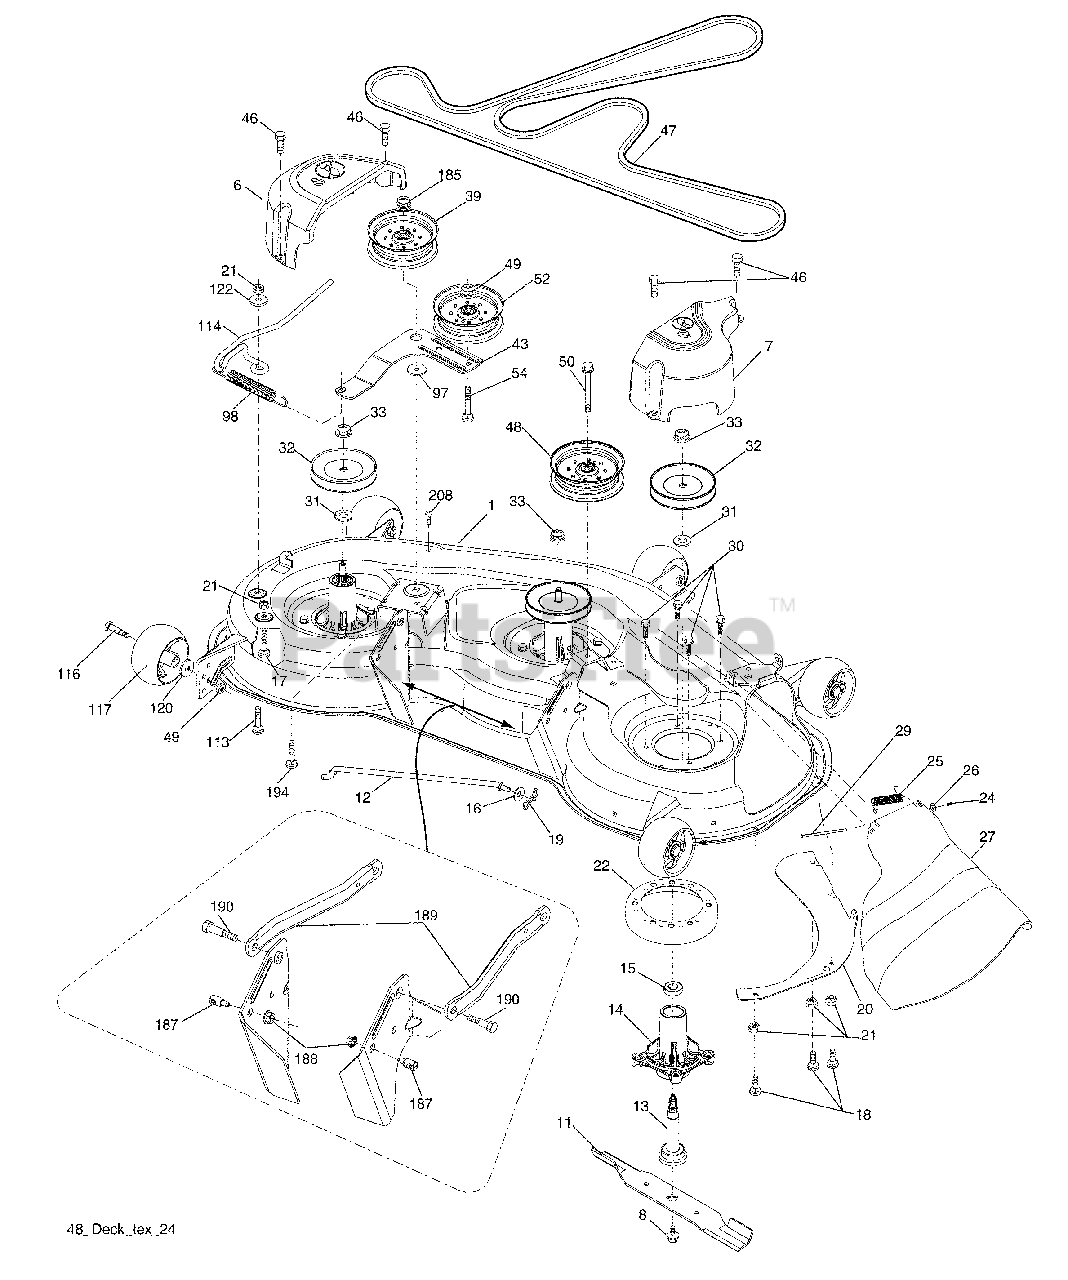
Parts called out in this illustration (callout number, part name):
1	Deck Weldment Mower
6	Cover Mandrel LH
7	Cover Mandrel RH
8	Bolt 7/16 Asm. Blade
11	Blade High Lift
12	Rod Anti-Sway
13	Shaft Asm. w/Lower Bearing
14	Housing, Mandrel
15	Bearing, Ball, Mandrel
16	Washer 13/32 x 13/16 x 12 Ga.
17	Bolt Carriage 5/16-18 x 5/8
18	Bolt RdHd 5/16-18 unc x 5/8
19	Pin Cotter 5/16 Bowtie Lock
20	Baffle Vortex Mower
21	Nut, Crownlock 5/16-18 unc
22	Stripper Mandrel Deck
24	Cap Sleeve
25	Spring, Torsion
27	Deflector Shield
29	Rod, Hinge
30	Screw, Thdroll Washer Head
31	Washer, Spacer Mower Vented
32	Pulley, Mandrel
33	Nut, Flg. Top Lock
39	Pulley, Idler, 4.50
43	Arm, Idler
46	Screw, Thdroll. 1/4-20 x 5/8
47	Belt Deck Drive
48	Pulley Idler Clutching
49	Nut, Lock Flg. 3/8-16 unc
50	Bolt Carriage 3/8-16 x 1-1/2 Gr. 5
52	Pulley Idler
54	Screw 3/8-16 x 2-1/4
97	Washer Hardened
98	Spring Drive
113	Bolt Rdhd Sqnk 5/16-18 x 3/4
114	Rod Tension Relief
116	Bolt, Shoulder
117	Gauge Wheel
120	Washer 13/32 x 1-1/4 x 12 Ga.
122	Bushing Tension Relief
185	Nut Lock Flange 7/16-14 Gr. 5
187	Stud Fastener w/"D" Anti-Rotation
188	Nut Lock Hex Flange
189	Arm Susp. Mower Rear
190	Bolt Shoulder
194	Bolt Carr Sqnk 7/16-24 x 2
208	Screw THDROL 3/8-16 x 1/2
